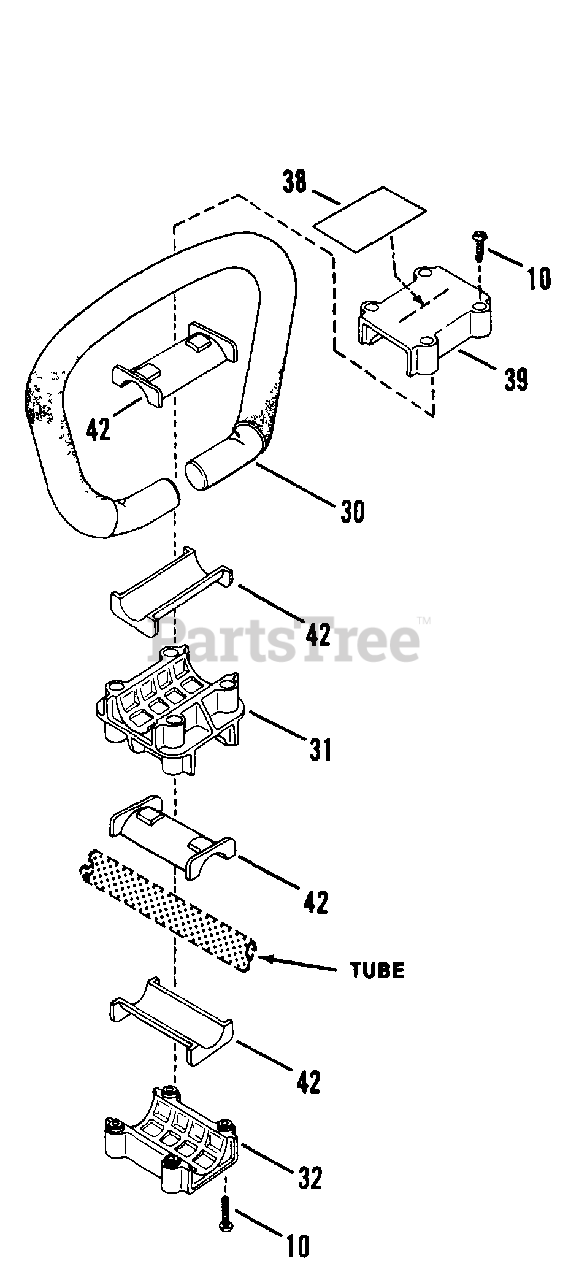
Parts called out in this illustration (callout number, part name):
10	SCREW, #10-16 x 3/4"
30	HANDLE ASSM'Y.,Loop
31	HANDLE MOUNT, Center
32	HANDLE MOUNT, Cap
38	DECAL, Replacement Part
39	HANDLE MOUNT ASSEMBLY
42	ISO-MOUNT (4)
